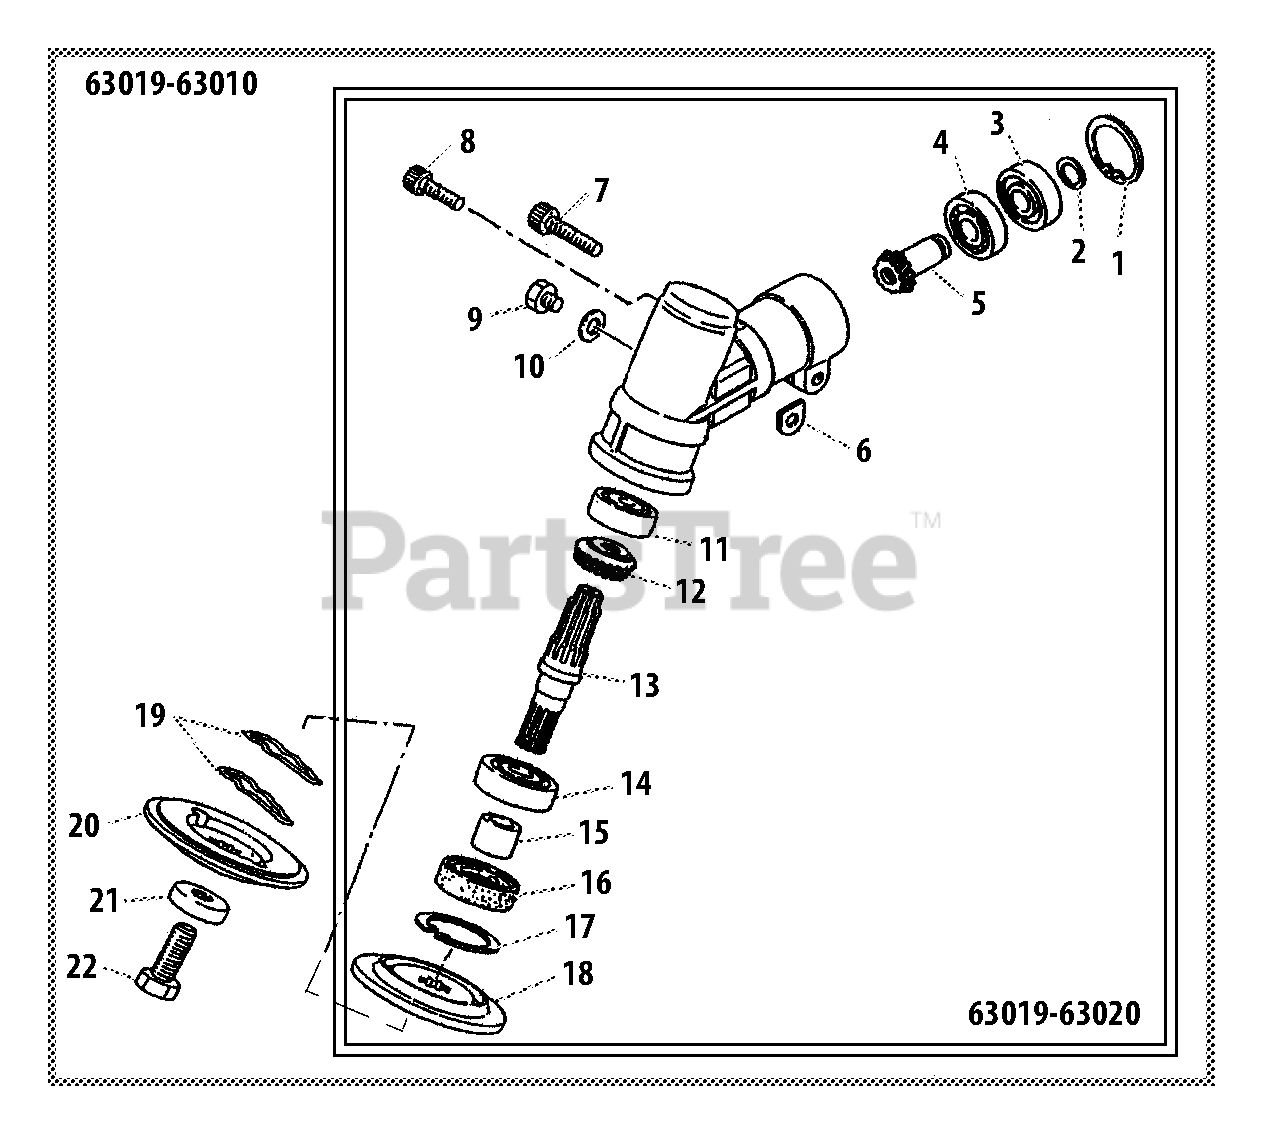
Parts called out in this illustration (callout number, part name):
1	RING, RETAINING - 28
2	RING, RETAINING
3	BEARING, BALL - 6001ZZ
4	BEARING, BALL - 6001
5	GEAR - SHAFT
6	SHIM
7	SCREW - 6X28
8	SCREW - 6X14
9	BOLT - 6X10
10	WASHER
11	BEARING, BALL - 6000DDU
12	GEAR - BEVEL
13	GEAR - SHAFT
14	BEARING, BALL - 6202
15	COLLAR
16	SEAL, OIL
17	RING, RETAINING - 35
18	HOLDER (A)
19	SLIDE PIN
20	HOLDER (B)
21	GUARD
22	BOLT - 10 -- LEFT HAND
63019-63010	GEAR CASE ASSY
63019-63020	GEAR CASE ASSY
